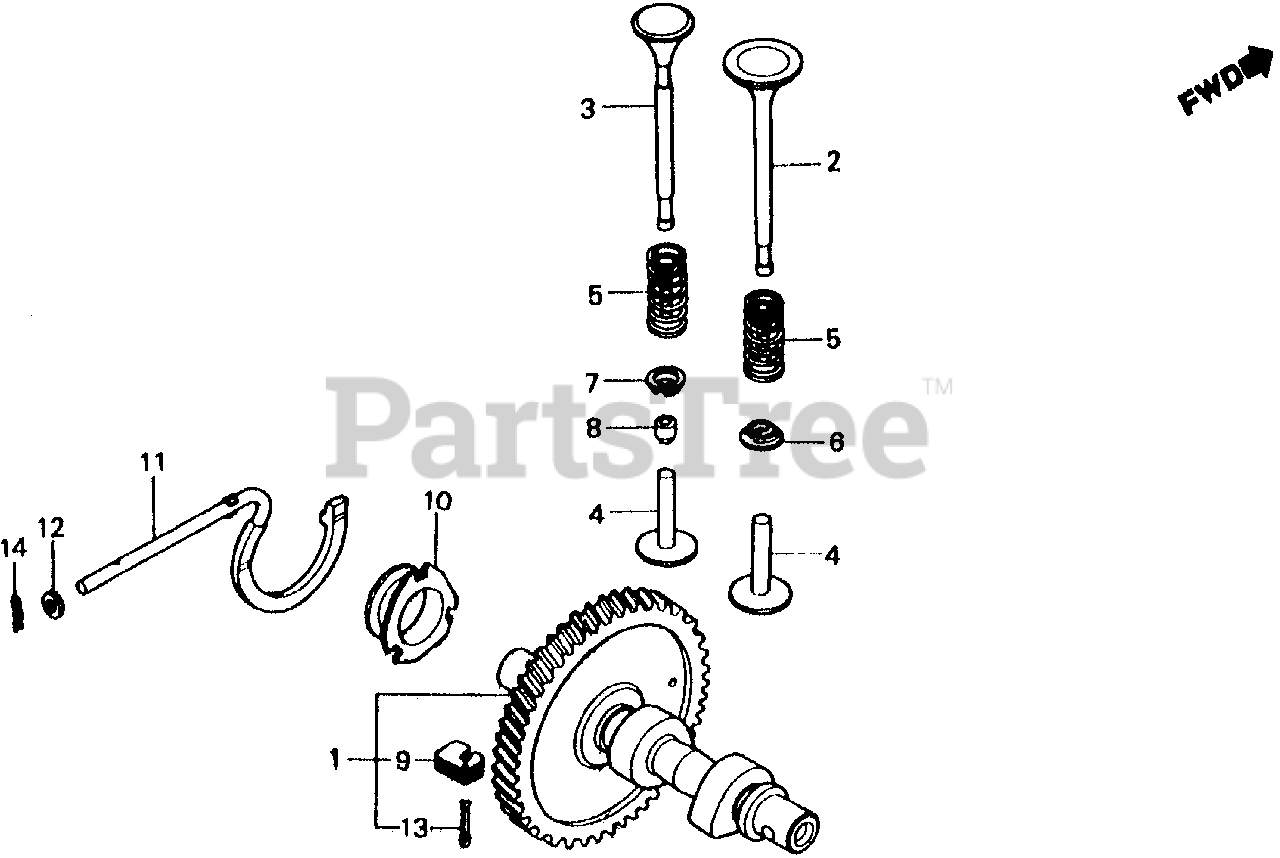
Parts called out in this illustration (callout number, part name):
1	CAMSHAFT (NOT AVAILABLE)
2	VALVE, IN.
3	VALVE, EX.
4	LIFTER, VALVE (45.89MM)
4	LIFTER, VALVE (46.04MM)
4	LIFTER, VALVE (46.19MM)
4	LIFTER, VALVE (46.34MM)
5	SPRING, VALVE
6	RETAINER, VALVE SPRING
7	RETAINER, VALVE SPRING
8	ROTATOR, EX. VALVE
9	WEIGHT, GOVERNOR (NOT AVAILABLE)
10	SLIDER, GOVERNOR
11	SHAFT, GOVERNOR
12	WASHER, PLAIN (6MM)
13	PIN, COTTER (3.0X15)
14	PIN, LOCK (10MM)
